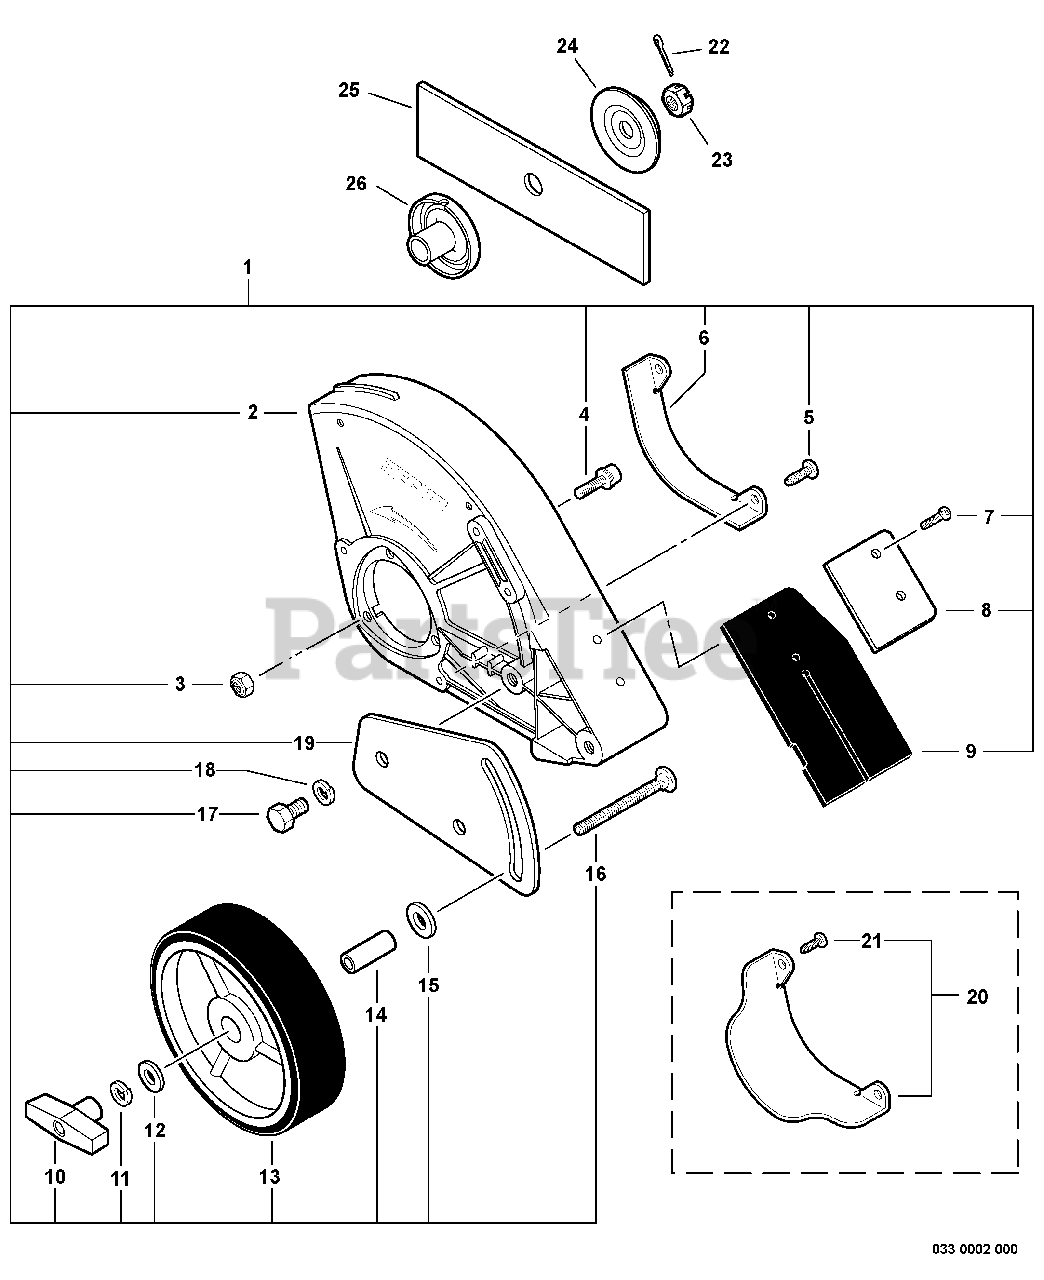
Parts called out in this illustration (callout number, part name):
1	EDGER SHIELD KIT
2	SHIELD, BLADE
3	LOCKNUT - 5
4	SCREW - 5X25
5	SCREW - 4X12 -- TAPPING
7	SCREW - 4X12 -- TAPPING
8	PLATE, FLAP
9	FLAP, DEBRIS
10	WINGNUT - 5/16-18
11	LOCKWASHER - 8
12	WASHER - 8
13	WHEEL - 6X1.5
14	COLLAR - 12
15	WASHER - 10
16	BOLT - CARRIAGE
17	BOLT - 8X14
18	LOCKWASHER - 8
19	BRACKET, WHEEL
20	SHIELD GUARD KIT
21	SCREW - 4X12 -- TAPPING
22	PIN, SPLIT - 2X22
23	LOCKNUT - LEFT HAND
24	ADAPTOR, BLADE - LOWER
25	BLADE, EDGER
26	ADAPTOR, BLADE - UPPER
